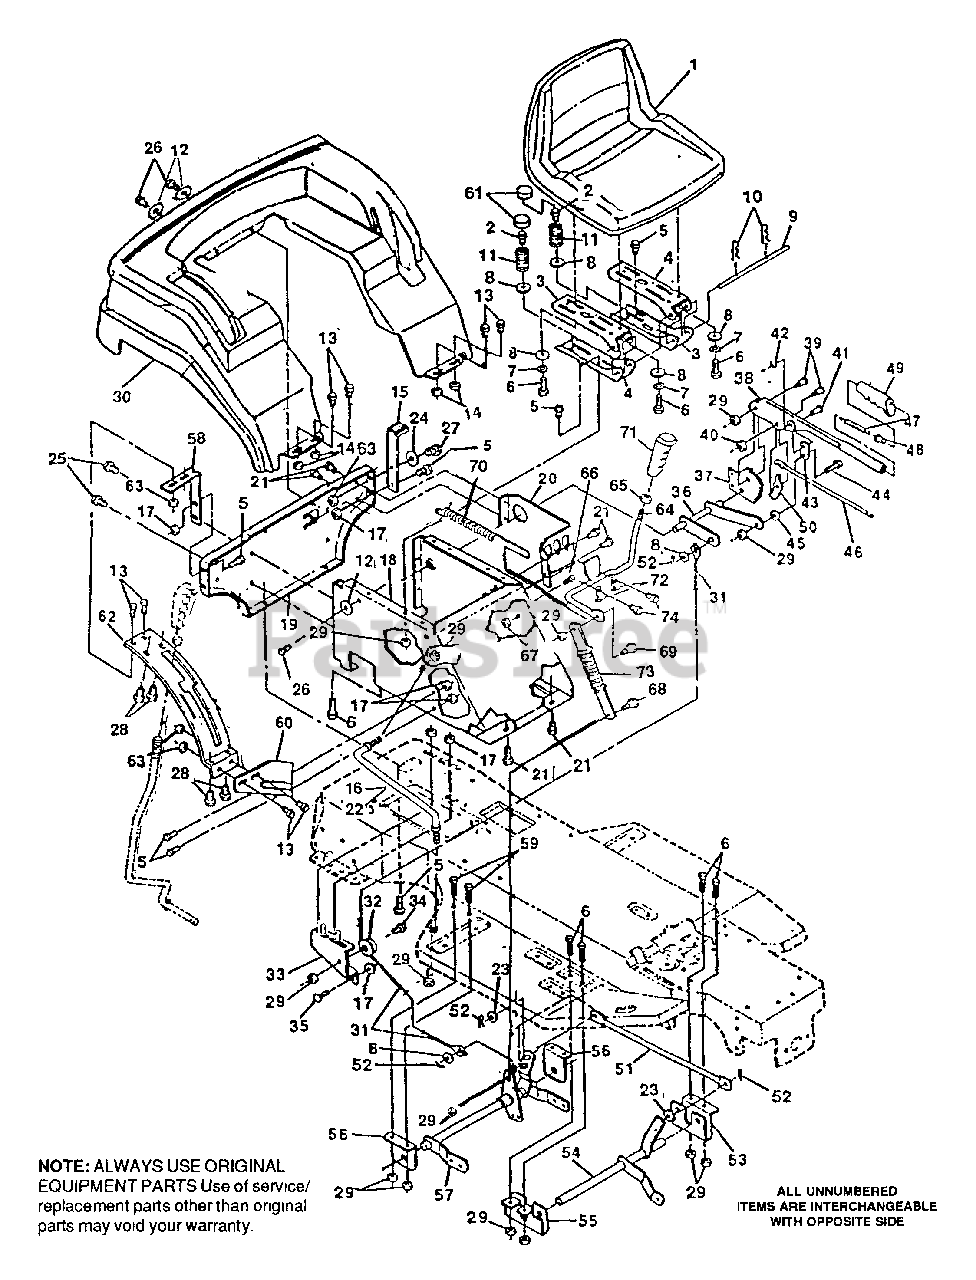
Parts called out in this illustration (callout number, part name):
2	Screw, 5/16 18 x .63
3	Channel, Seat L.H
4	Channel, Seat R.H.
5	Screw, Hx Hd, Wd Fl 5/16-18 x 3/4 In.
6	Screw, Hx Hd, 5/16-18 x 3/4 In.
7	Washer, Lock 5/16 In.
8	Washer, Flat, 11/32 In.
9	Rod, Seat Support
10	Hair Pin, .073 Dia. x 1.13 In.
11	Seat Spring
12	Washer, Flat, 9/32 In.
13	Screw, Hx Hd, 1/4-20 x 5/8 In.
14	Nut, Lock, 1/4-20 Thd.
15	Fende Support, L. H.
16	Support, LH footrest stiffener
17	Nut, Hx, Wd Fl, Lk 5/16-18 Thd.
18	Seat Support
19	Support, Fender & Seat
20	Bracket, Support Engage
21	Screw, Hx Wshr Hd Tap, 5/16-18 x 1/2 In.
22	Support, LH footrest stiffener
23	Flatwasher, 13/32 In.
24	Flatwasher
25	Screw, Tap, 5/16-18 x 7/8 1
26	Screw, Hx, Wshr Hd, Tap 1/4-20 x 5/8 In.
27	Screw, 1/4-20 x 3/4 In.
28	Screw, Hx Hd, Tap #10 x 1/2 In.
29	Nut, Hx Ctrlk, 5/16-18 Thd.
30	Fender
31	Cable, Deck Lift
33	Assembly, Pulley Bracket
34	Shoulder Bolt, 5/16-18 Thd.
35	Bolt, Carriage, 5/16-18 x 5/8 In.
36	Assembly, Upper Shaft
38	Lift Lever
39	Shoulder Bolt, 5/16-18 Thd.
40	Nut, Hx Wd Fl Lk 5/16-18 Thd.
41	Clevis Pin
44	Shoulder Bolt, 5/16-18 Thd.
46	Actuator Rod
47	Spring, Height Adjust
48	Knob, Height Adjust
49	Handle, Lift
50	Pawl, Height Adjust
52	Cotter Pin
53	Bracket, L. H. Front Hanger
54	Assembly, Front Lift Shaft
55	Bracket, R. H. Front Hanger
56	Bracket, Hanger
57	Assembly, Rear Lift Shaft
58	Fender Support, R. H.
59	Screw, Hx Hd, 5/16-18 x 5/8 In.
60	Support, Shift Plate
61	Cover, Seat Spring
63	Nut, Hx, Wd Fl Lk, 1/4-20 Thd.
64	Assembly brkt & Engagement hand
65	Nut, HX Ctrlk, 1/2-13 Thd.
66	Screw, Hex, 3/8-16x2-1/4 In.
67	Nut, Hex Keps, 3/8-16 Thd.
68	Bolt, .437x .156 Hhsh 5/16-18
69	Bolt, Shoulder, 7/16 In.
70	Spring, Tension
71	Handle, Lift
73	Assembly, Spring Cartridge
74	Screw, 1 /4-20x 1/2 In.
